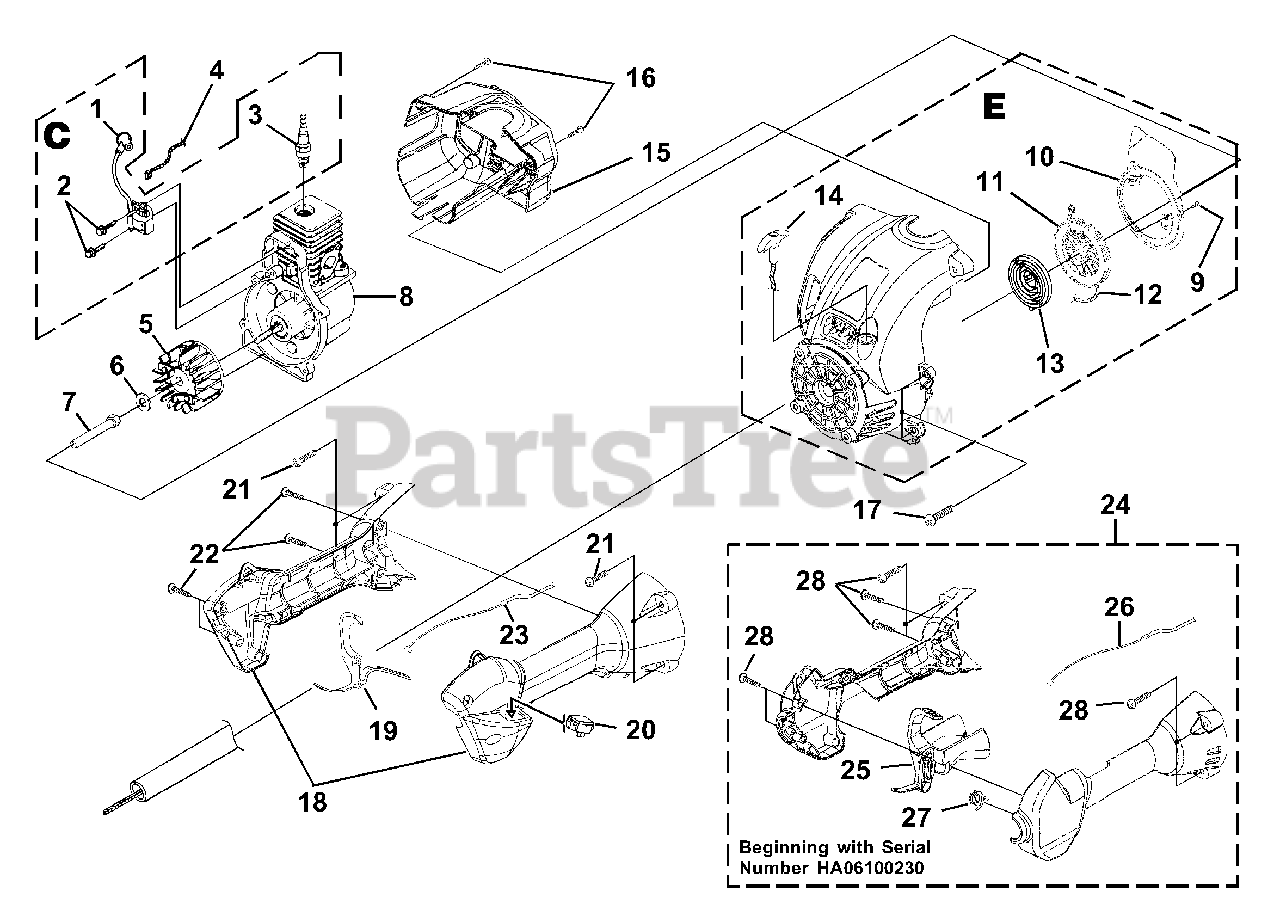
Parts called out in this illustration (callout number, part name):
1	TERMINAL & COVER
2	SCREW-Taptite (8-32 X 1")
3	SPARK PLUG
4	LEAD-Electrical
5	ROTOR KIT
6	WASHER-Flat
7	CONNECTOR-Drive (.250)
8	SHORT BLOCK
9	SCREW-Thread Form (8-16 X 1/2")
10	BAFFLE-Air
11	PULLEY-Starter
12	ROPE-Starter (42")
13	SPRING & CONTAINER
14	GRIP-Starter (Yellow)
15	HOUSING-Rear Kit
16	SCREW-Taptite (10-14 X 7/8")
17	SCREW-Taptite (10-24 X 3/4")
18	CONTROL HANDLE ASSY.
19	TRIGGER-Throttle
20	PLUG-Switch
21	SCREW-Taptite (10-14 X 7/8")
22	SCREW-Truss Hd. (10-14 x 1")
23	CABLE-Throttle
24	CONTROL HANDLE ASSY.
25	TRIGGER
26	CABLE-Throttle
27	SPRING
28	SCREW-Truss Hd. (10-14 x 1")
C	IGNITION KIT
E	COMPLETE STARTER ASSEMBLY
